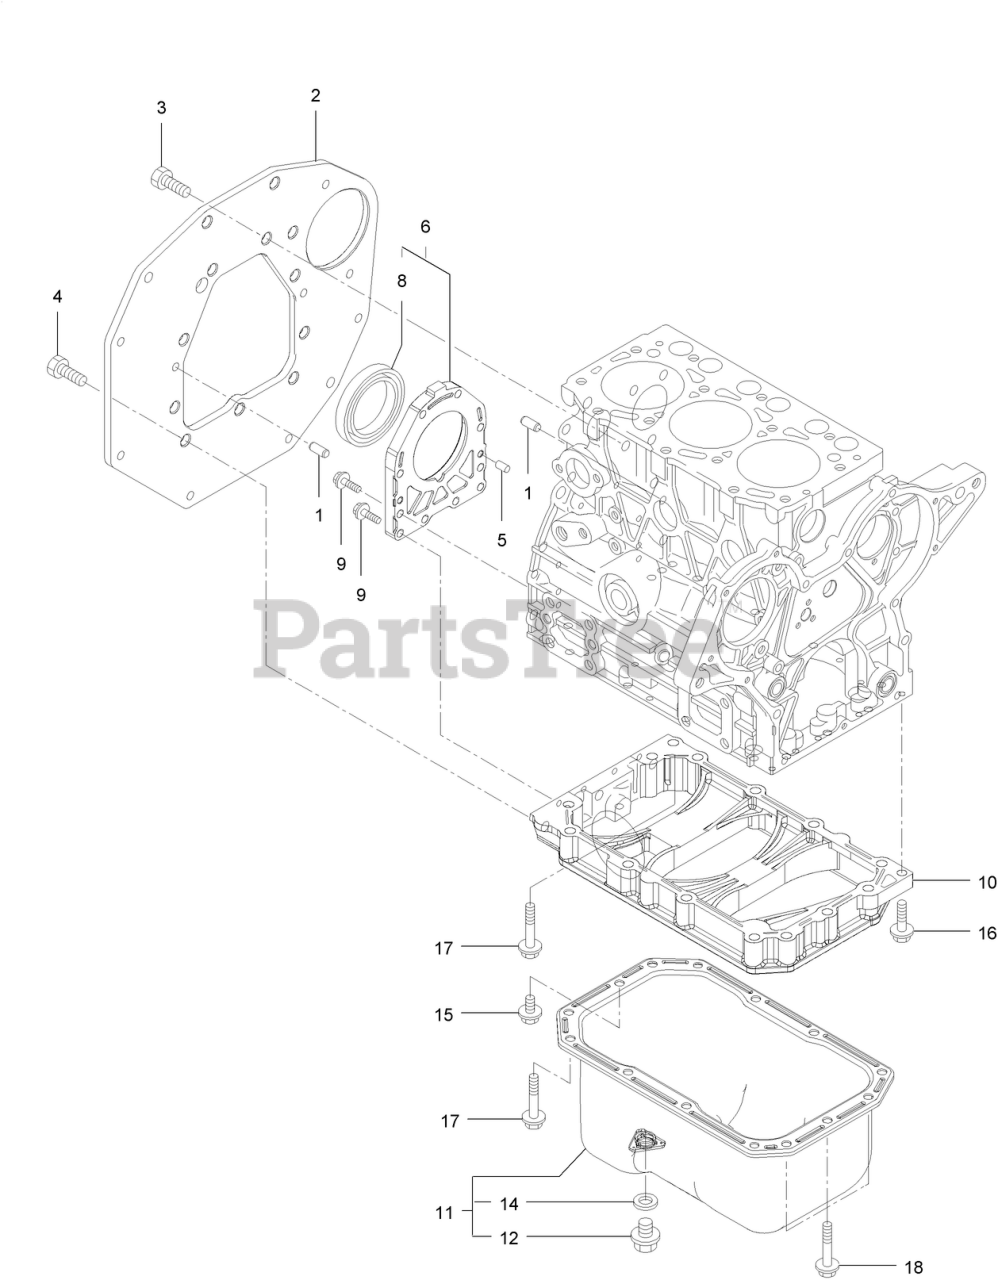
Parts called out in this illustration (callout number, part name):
2	FLANGE-MOUNTING
5	PIN-PARALLEL
6	CASE ASM-OIL SEAL
8	SEAL-OIL
10	SPACER-OIL PAN
11	OIL PAN ASM
14	WASHER-SEAL
